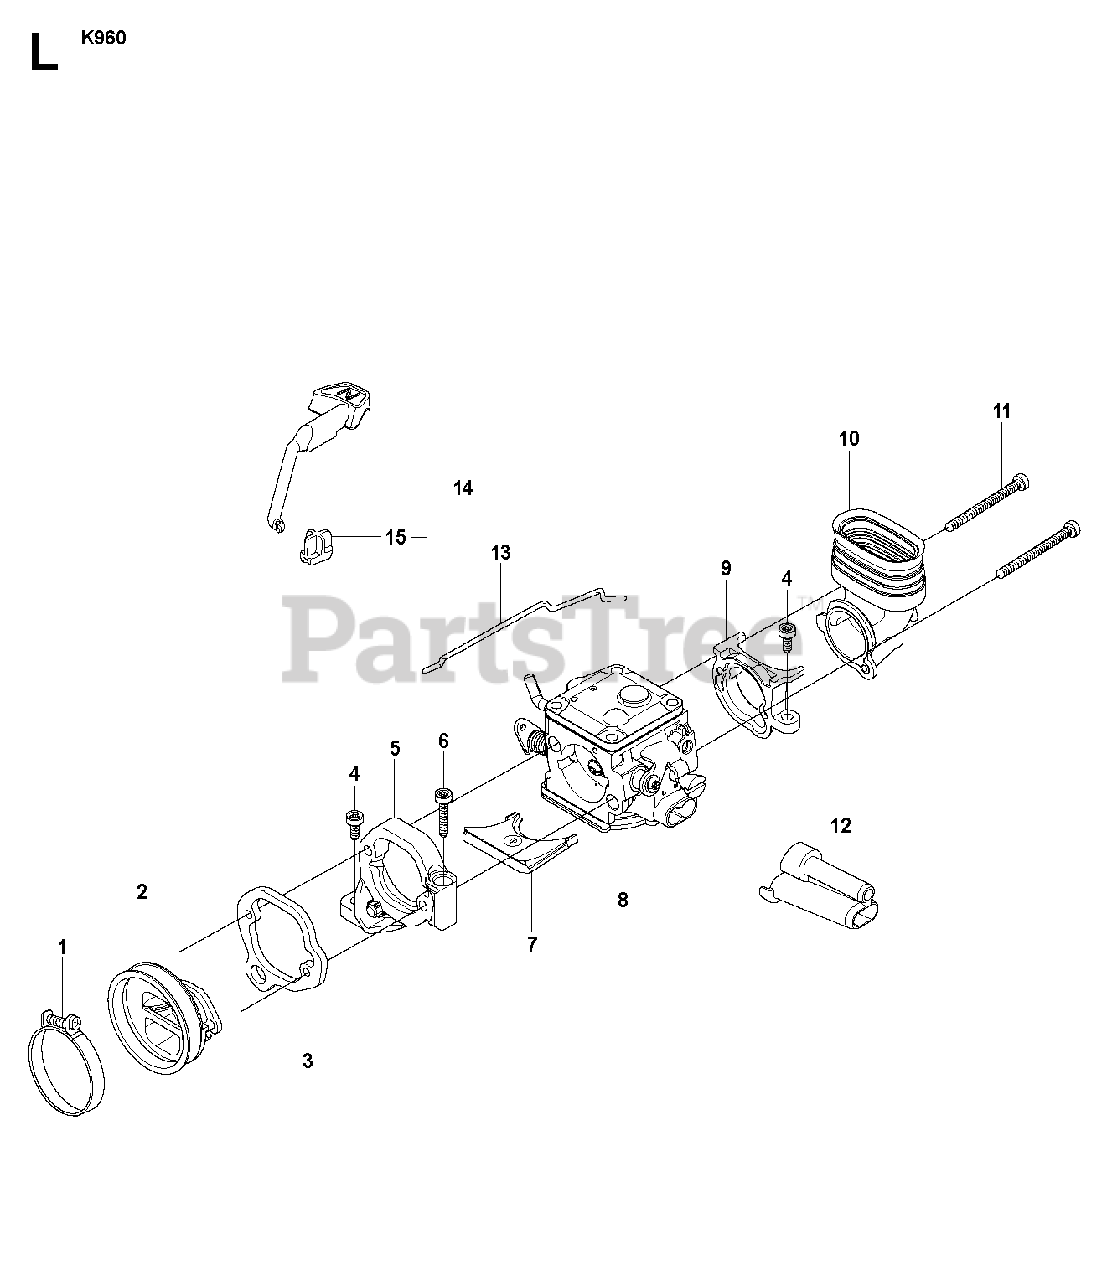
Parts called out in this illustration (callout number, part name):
1	HOSE CLAMP
4	SCREW ITXSCM
6	SCREW ITXSCM
8	CARBURETTORWalbro RWJ-2
11	SCREW ITXSCM
12	CHISEL GUIDE
13	THROTTLE ROD
14	CHOKEIncl. 15
15	WEAR PROTECTION
